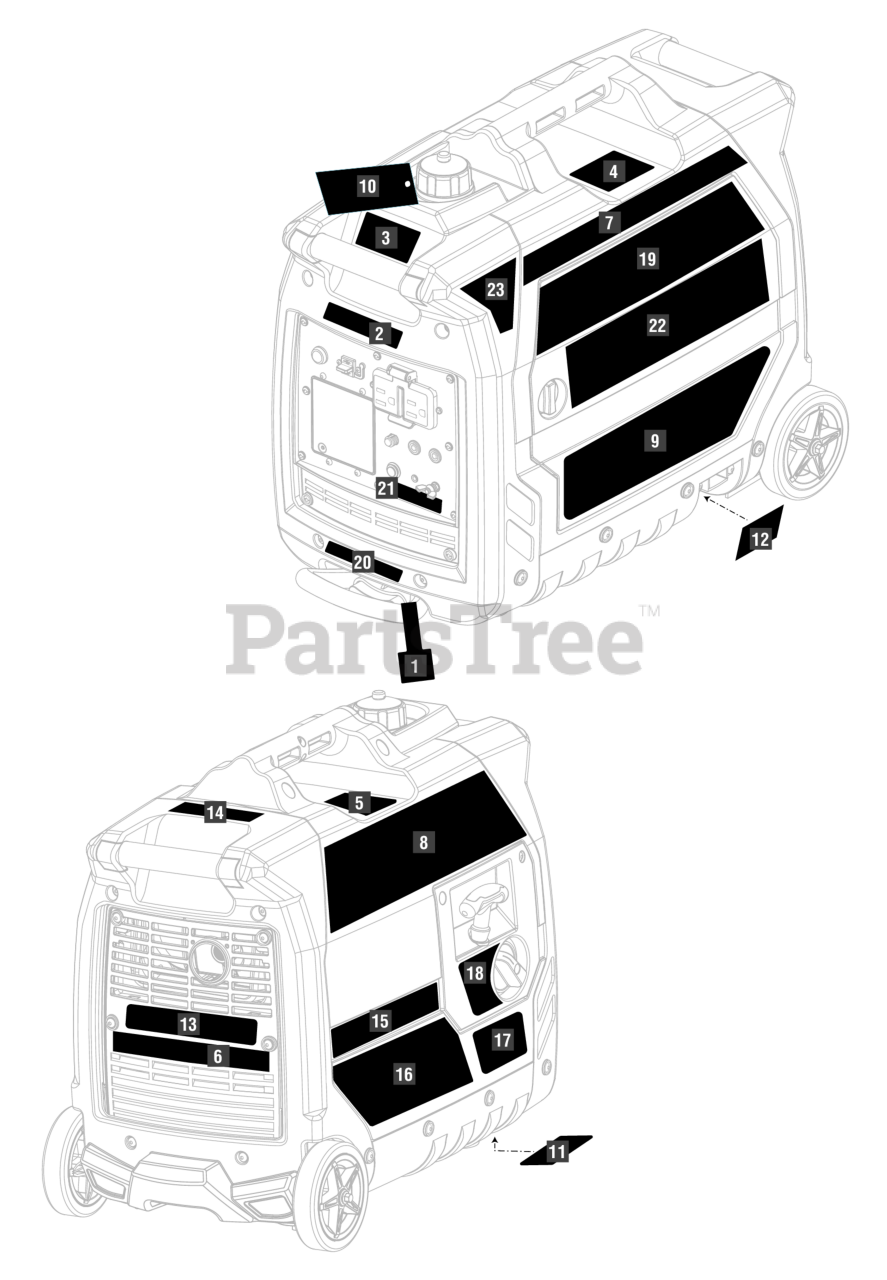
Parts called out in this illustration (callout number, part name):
1	Button Handle Release Label
2	Logo Label
3	Fuel Stabilizer Label
4	CPSC Danger Label
5	Danger Label
6	Ground Warning Label (En/Fr)
7	Fire Distance Label
8	Performance Label (Maintenance Door)
9	Inquiries Label
10	Warning Hangtag
11	Upright Storage Label
12	Internally Placed Maintance Label
13	Combustion Label
14	Exhaust Direction Label
15	Start Label
16	Gen Control/Bluetooth Label
17	Co Detect/Easy Start Logo Label
18	Choke Label
19	Performance Label
20	FCC ID Label
21	LED Light Legend Label
22	CO Automatic Shut Down Label
23	Do Not Tamper Warning Label
